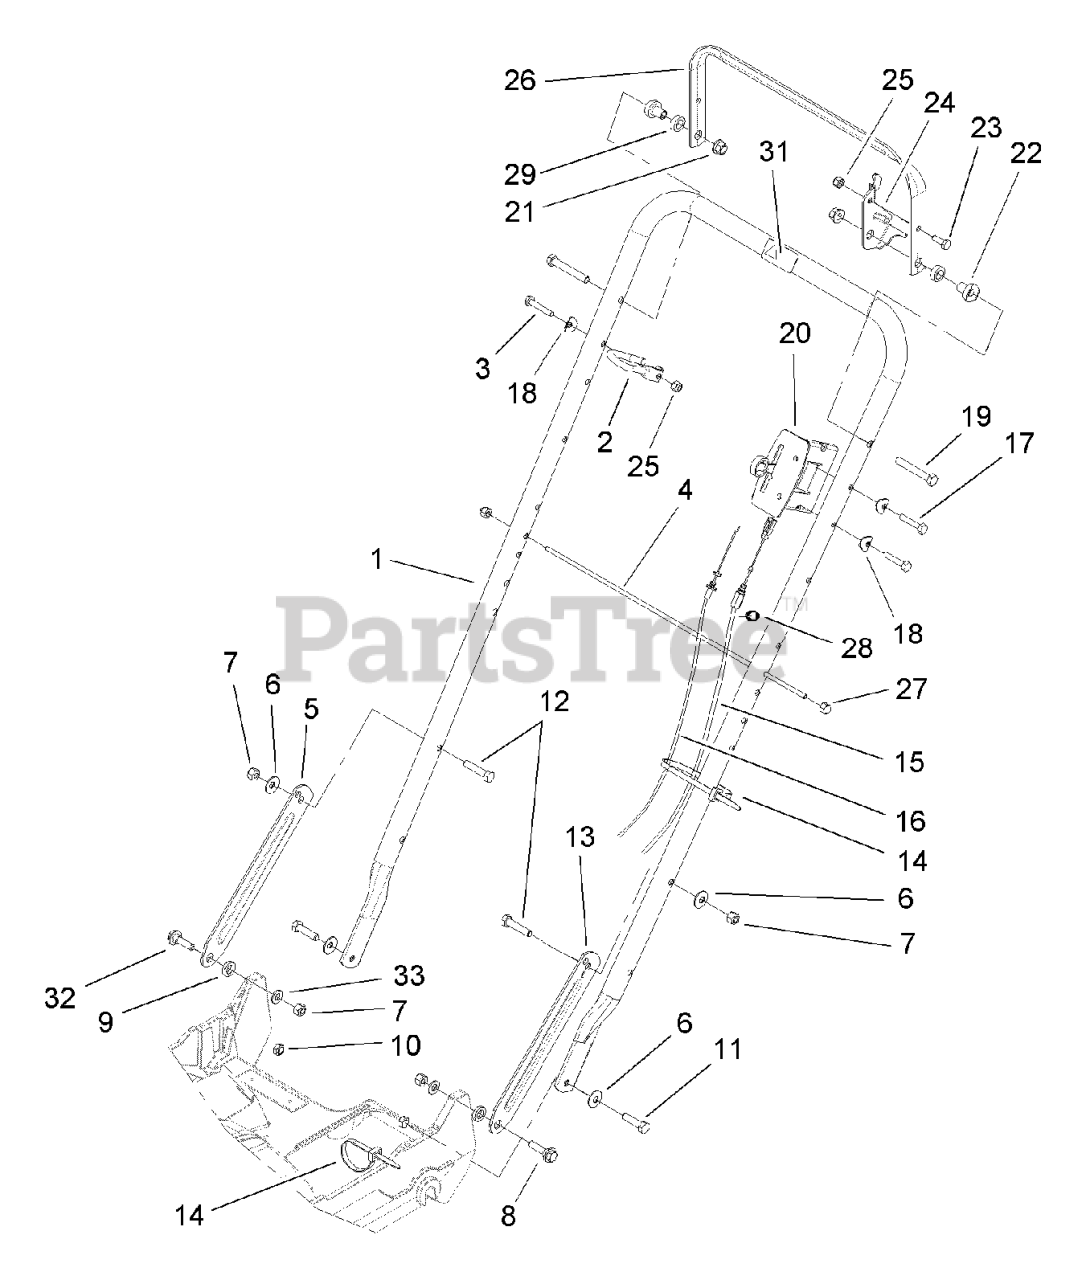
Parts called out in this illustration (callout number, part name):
2	GUIDE-ROPE
3	SCREW-HH
4	ROD-SUPPORT, BAG
6	WASHER-BELLEVILLE
7	NUT-LOCK, NI
8	SCREW-SHOULDER
9	SPACER
10	NUT-LOCK, NI
11	SCREW-HH
12	SCREW-HH
14	TIE-CABLE
15	CABLE-BRAKE
16	THROTTLE CABLE ASM
17	SCREW-HH
18	WASHER
19	SCREW-HH
21	NUT-LOCK, NI
22	SPACER-SUPPORT
23	SCREW-HH
24	LEVER-CONTROL
25	NUT-LOCK, NI
26	BAR-CONTROL
27	NUT-CAP
29	SPACER-NYLON
31	DECAL-PROTECTION, HEARING
32	SCREW-SHOULDER
33	WASHER-PLAIN
